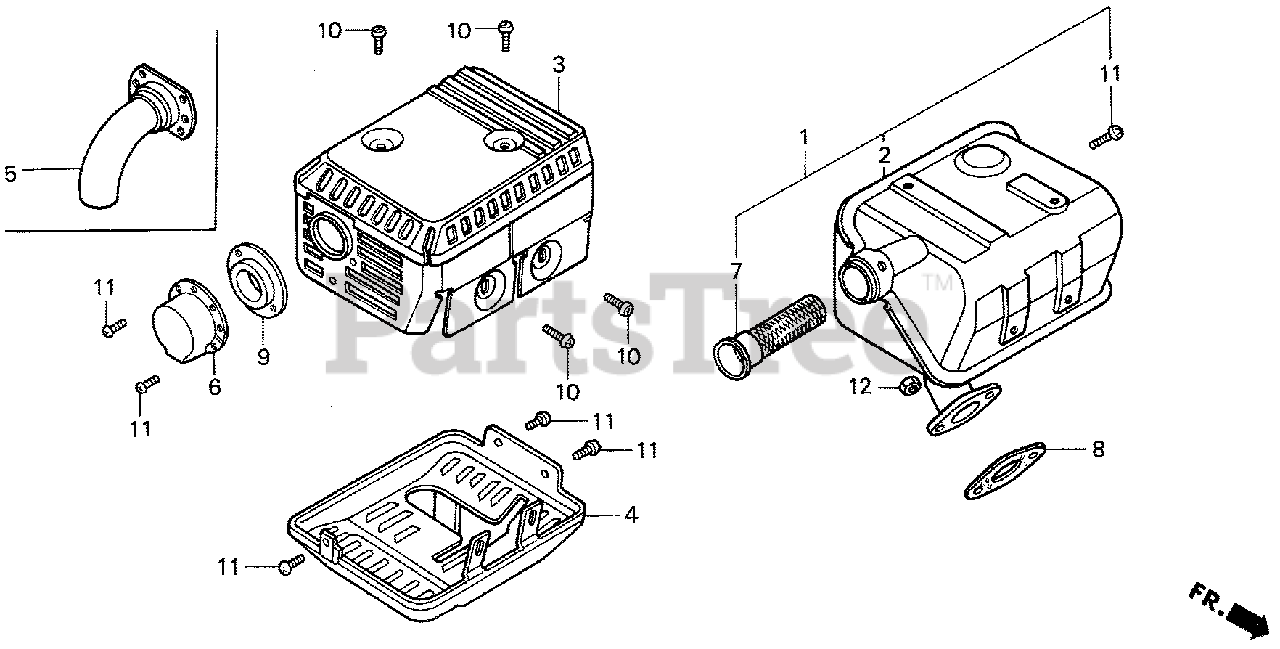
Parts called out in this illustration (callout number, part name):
1	MUFFLER (ARRESTER)
3	PROTECTOR (UPPER)
3	PROTECTOR, MUFFLER
7	ARRESTER, SPARK
8	GASKET, MUFFLER
10	SCREW, TAPPING (5X8)
11	SCREW, TAPPING (4X6)
12	NUT, HEX. (8MM)
